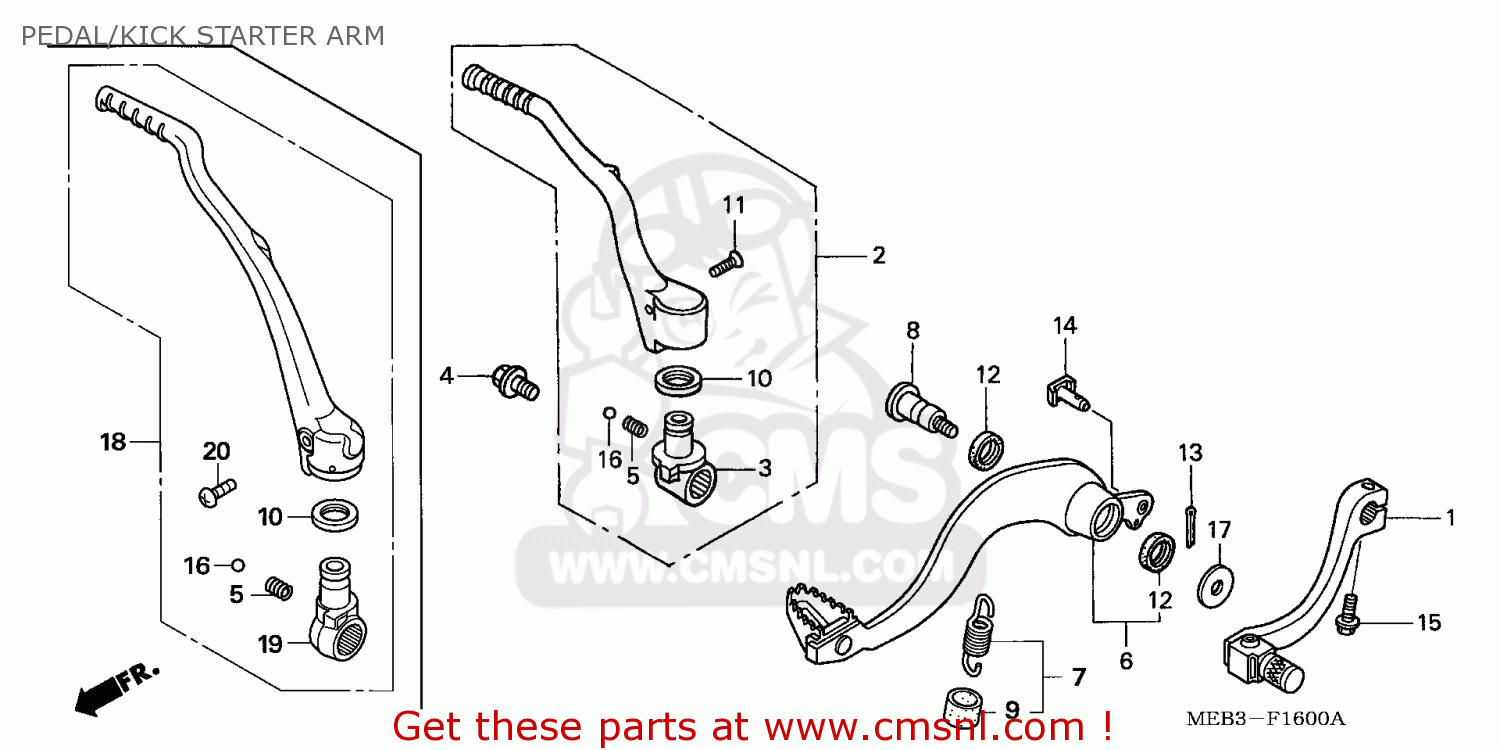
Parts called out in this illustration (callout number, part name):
1	PEDAL,COMP CHANGE
2	ARM ASSY,KICK STA
3	JOINT,KICK ARM
4	BOLT,KICK JOINT
5	SPG,START ARM SET
6	PEDAL COMP,RR BRA
7	SPG ASSY,RR BRAKE
8	SHAFT BRAKE PIVOT
9	TUBE,BRAKE PEDAL
10	DUST SEAL17X20X25
11	BOLT,KICK ARM
12	OIL SEAL
13	PIN,SPLIT2.0X12
14	PIN D,JOINT
15	BOLT,FLANGE,6X22
16	BALL,STEEL.,8
